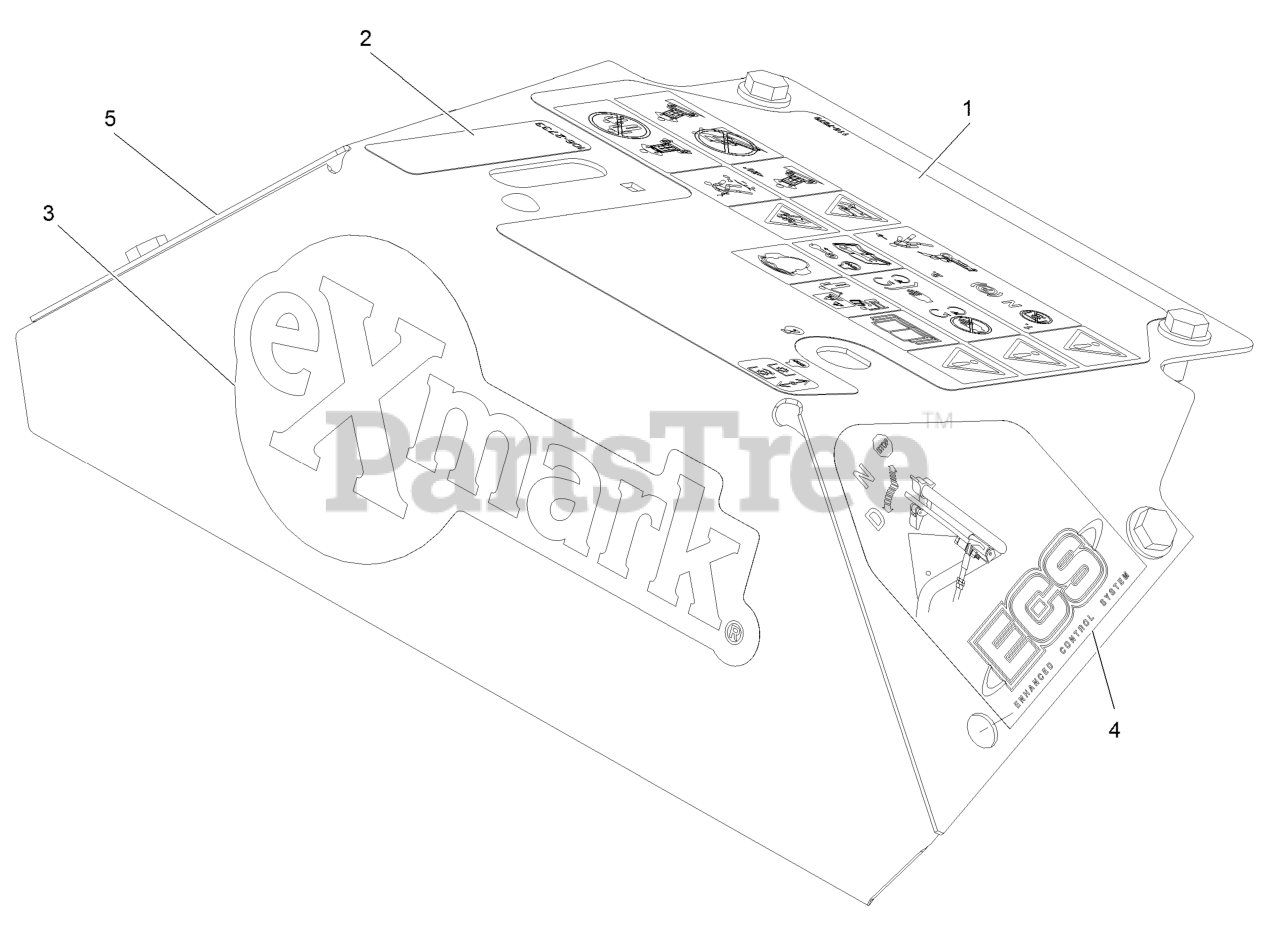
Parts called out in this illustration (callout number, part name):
1	DECAL-CONSOLE METRO ECS
2	DECAL-THROTTLE
3	DECAL,EXMARK LOGO
4	DECAL,LH ECS INSTRUCTION
5	DECAL,RH ECS INSTRUCTION
